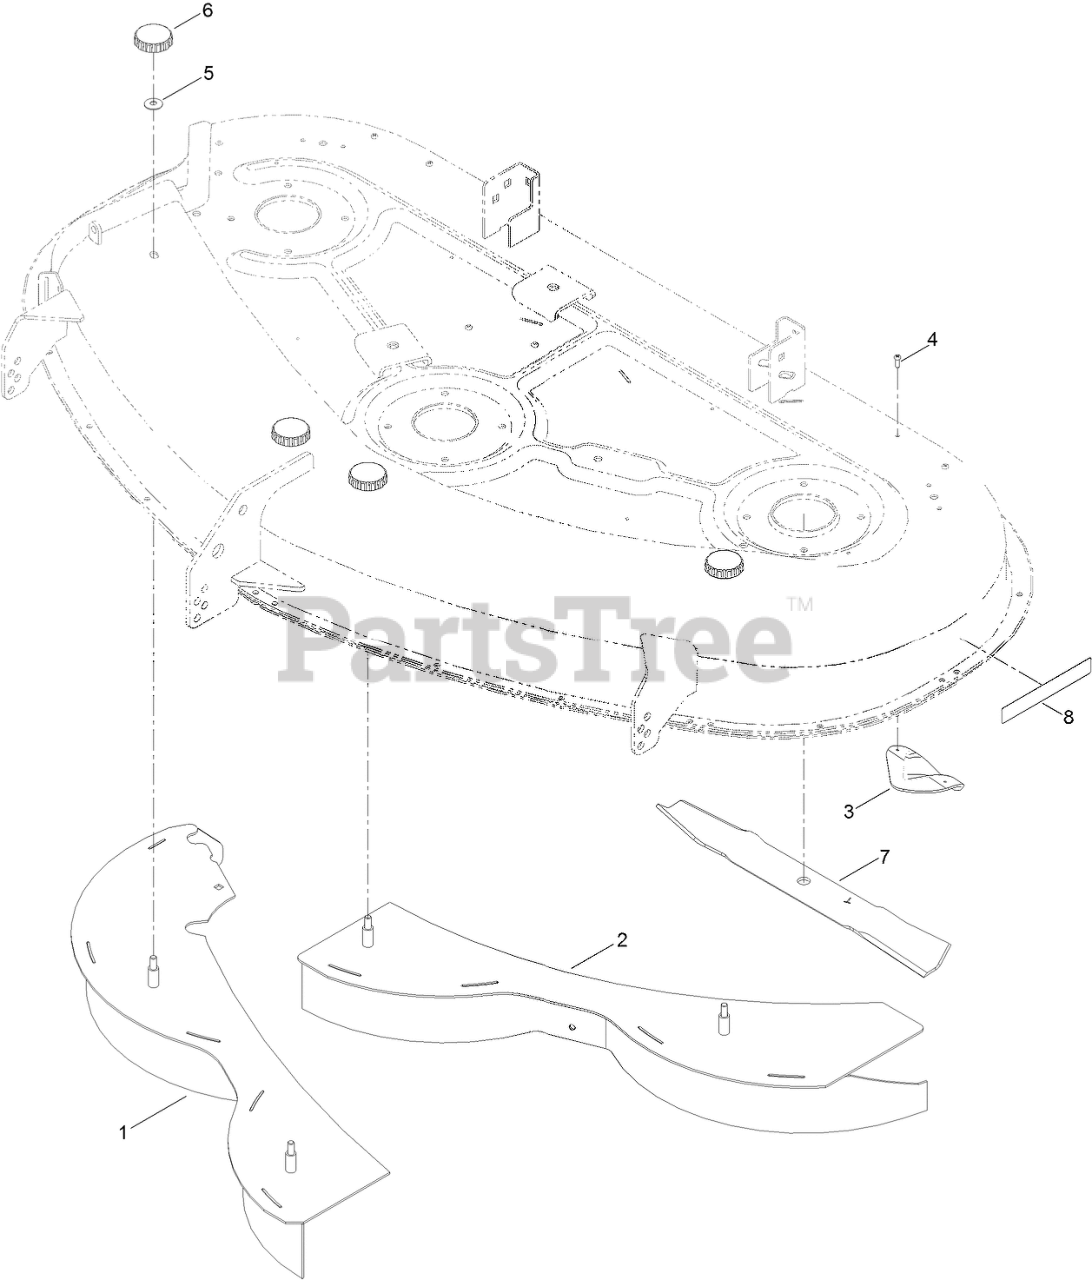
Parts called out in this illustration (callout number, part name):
1	RH BAFFLE ASM
2	LH BAFFLE ASM
3	PLATE-KICKER
4	SCREW-PPH
5	WASHER-BELLEVILLE
7	BLADE-MULCH, 18.75 INCH
8	DECAL-RECYCLER
